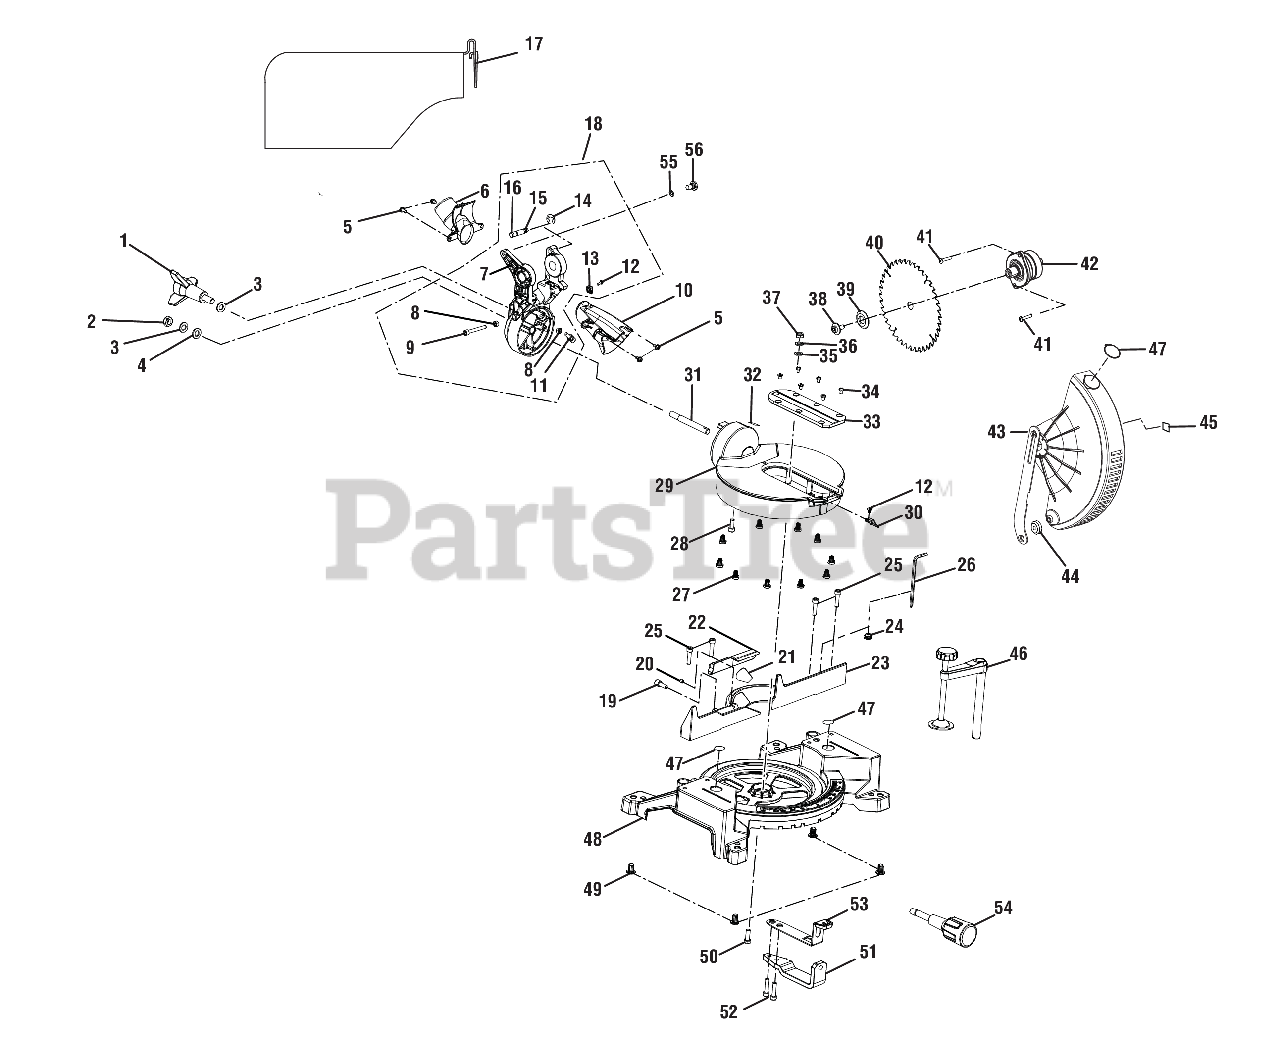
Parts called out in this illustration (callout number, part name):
1	Bevel Lock Knob w/Washer
2	Lock Nut (M10)
3	Washer (OD20 x ID105 mm x 2t)
4	Washer (OD188 x ID10 mm x 1t)
5	Screw (M4 x 12 mm)
6	Dust Chute Outlet
7	Bevel Knuckle
8	Nut w/Washer (M6)
9	Screw (M6 x 35 mm)
10	Dust Chute Intlet
11	Screw (M6 x 20 mm)
12	Screw (M4 x 8 mm)
13	Bevel Indicator
14	Clip (Ø?5)
15	Head Lock Pin
16	O-ring (45 × 18)
17	Dust Bag Assembly
18	Bevel Arm Assembly (Inc Key Nos 7-9 & 11-16)
19	Fence Lock Screw
20	Screw (M6 x 10 mm)
21	Sliding Fence Warning Label
22	Sliding Fence
23	Miter Fence (Inc Key No 21)
24	Spanner Holder
25	Screw (M6 x 25 mm)
26	Hex Key Wrench
27	Rubber Feet
28	Screw (M6 x 16 mm)
29	Miter Table Assembly (Inc Key No 32)
30	Miter Indicator
32	Bevel Scale Label
33	Throat Plate
34	Screw (M4 x 8 mm)
35	Washer (OD22 x ID8 mm x 3t)
36	Washer (OD16 x ID8 mm x 16t)
37	Lock Nut (M8)
38	Blade Screw (M8 x 16 mm)
39	Blade Washer
40	Blade (24t)
41	Screw (M5 x 16 mm)
42	Output Spindle Assembly
43	Lower Blade Guard Assembly (Inc Key Nos 44-45 & 47)
44	Lower Guard Wheel
45	Blade Screw Direction Label
46	Work Clamp Assembly
47	No Hands Label
48	Base Assembly (Inc Key No 47)
49	Rubber Feet
50	Screw (M8 x 25 mm)
51	Miter Support Arm
52	Screw (M6 x 25 mm)
53	Miter Detent Spring Assembly
54	Miter Lock Handle Assembly
55	Spring Washer
56	Plate Screw
